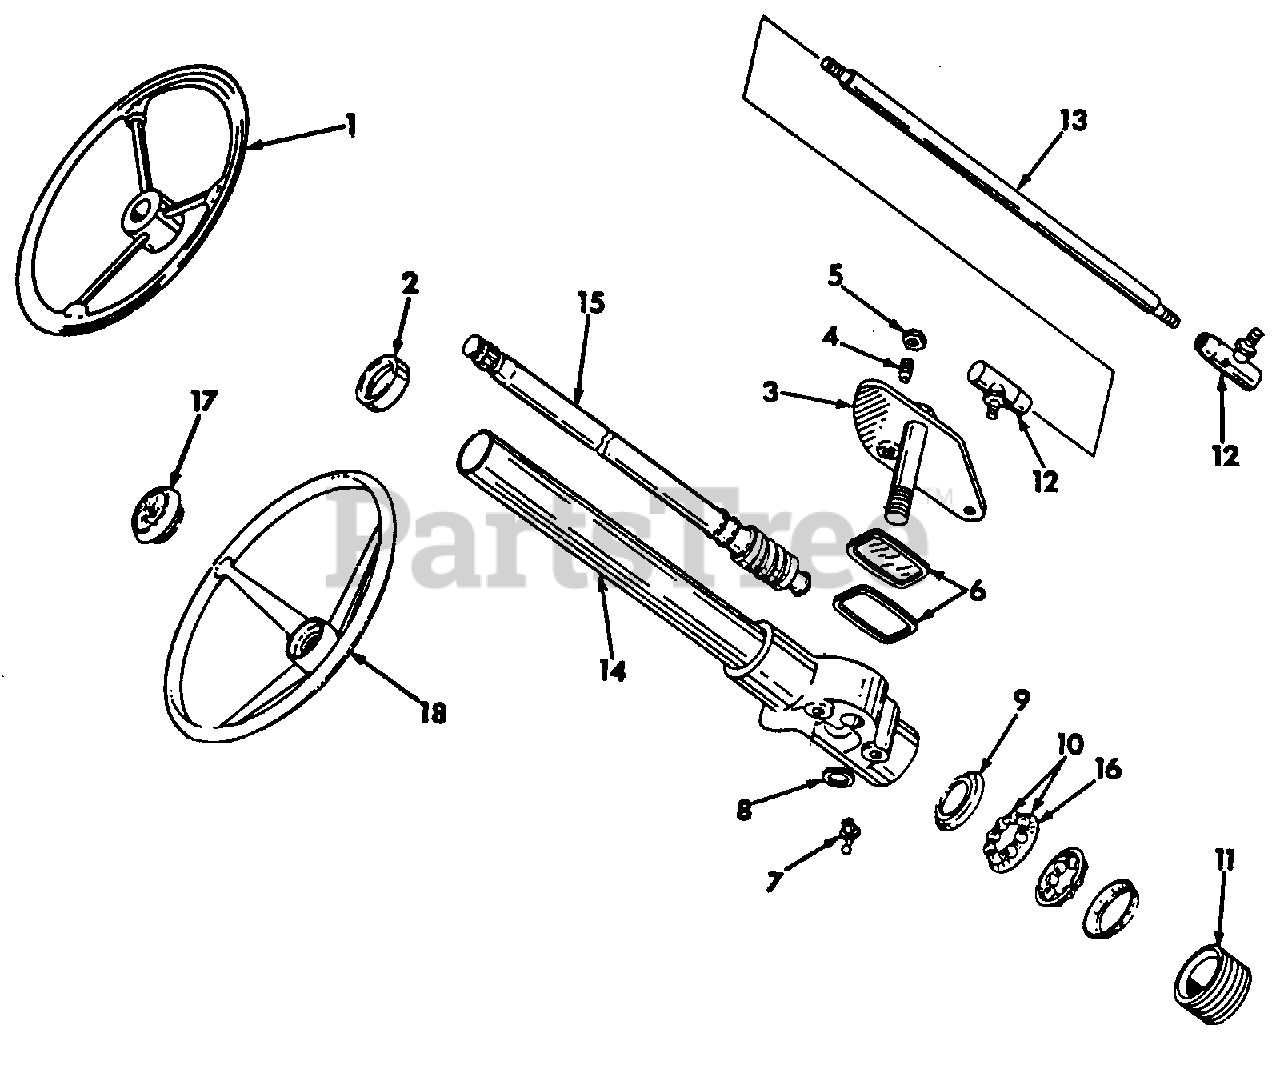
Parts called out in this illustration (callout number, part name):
1	Not used in this application
2	Bearing, Upper Column
3	Lever & Bolt Assy
4	Stud, Cam Follower
5	Nut, Cam Follower Stud
6	Package, Seal & Seal Retainer
7	Fitting, 1/4 65 Deg Angle Drive Lube
8	Washer, Flat C-Z
9	Retainer, Bearing Ball
10	Retainer & Ball Assy
11	Plug, Adjusting
12	Joint, Tie Rod End
13	Link, Steering Gear Drag
14	Tube Assy, Housing & Jacket
15	Cam & Tube Assy
16	Retainer, Ball
17	Cap, Steering Wheel
18	Wheel, Steering
